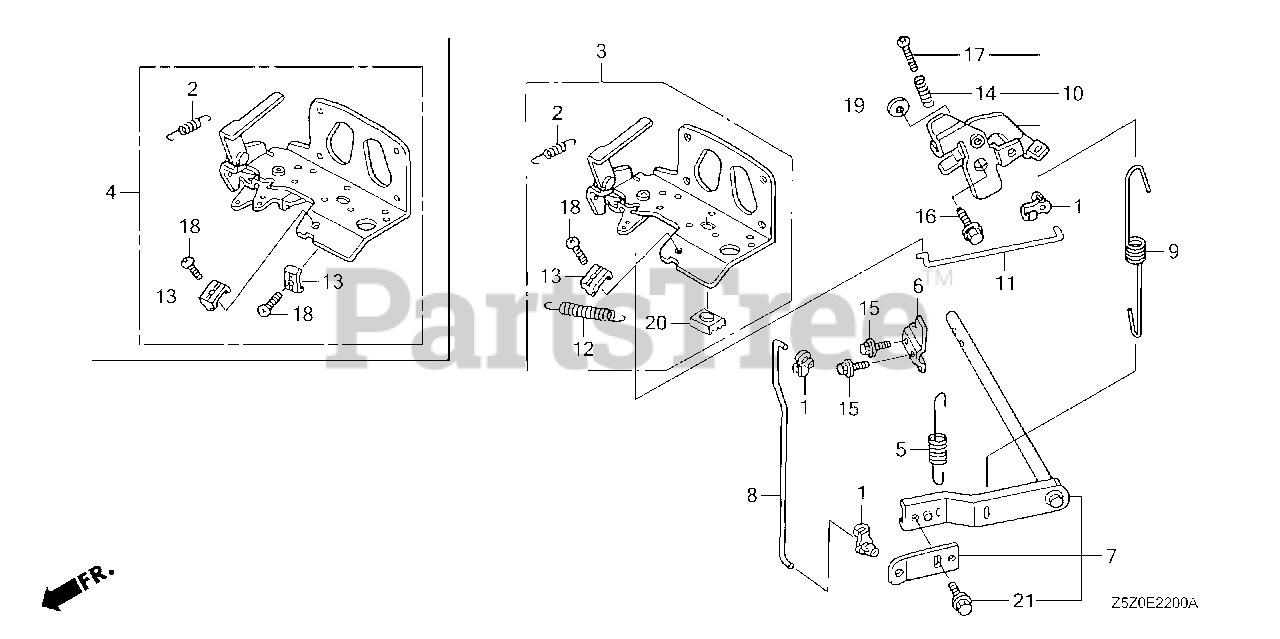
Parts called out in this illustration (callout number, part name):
1	ROD, JOINT
2	SPRING, CHOKE RETURN
4	CONTROL ASSY. (2-LEVER)
5	SPRING, STARTER
6	FORK, GOVERNOR
7	ARM, GOVERNOR
8	ROD, GOVERNOR
9	SPRING, GOVERNOR
10	LINK, GOVERNOR
11	ROD, GOVERNOR LINK
13	HOLDER, CABLE
14	SPRING, CONTROL ADJUSTING
15	BOLT, FLANGE (5X10)
16	BOLT, FLANGE (6MM) (CT200)
17	SCREW, RECESSED (5X25)
18	SCREW, PAN (5X16)
19	WASHER, PLAIN (6MM)
21	BOLT, FLANGE (6X10)
